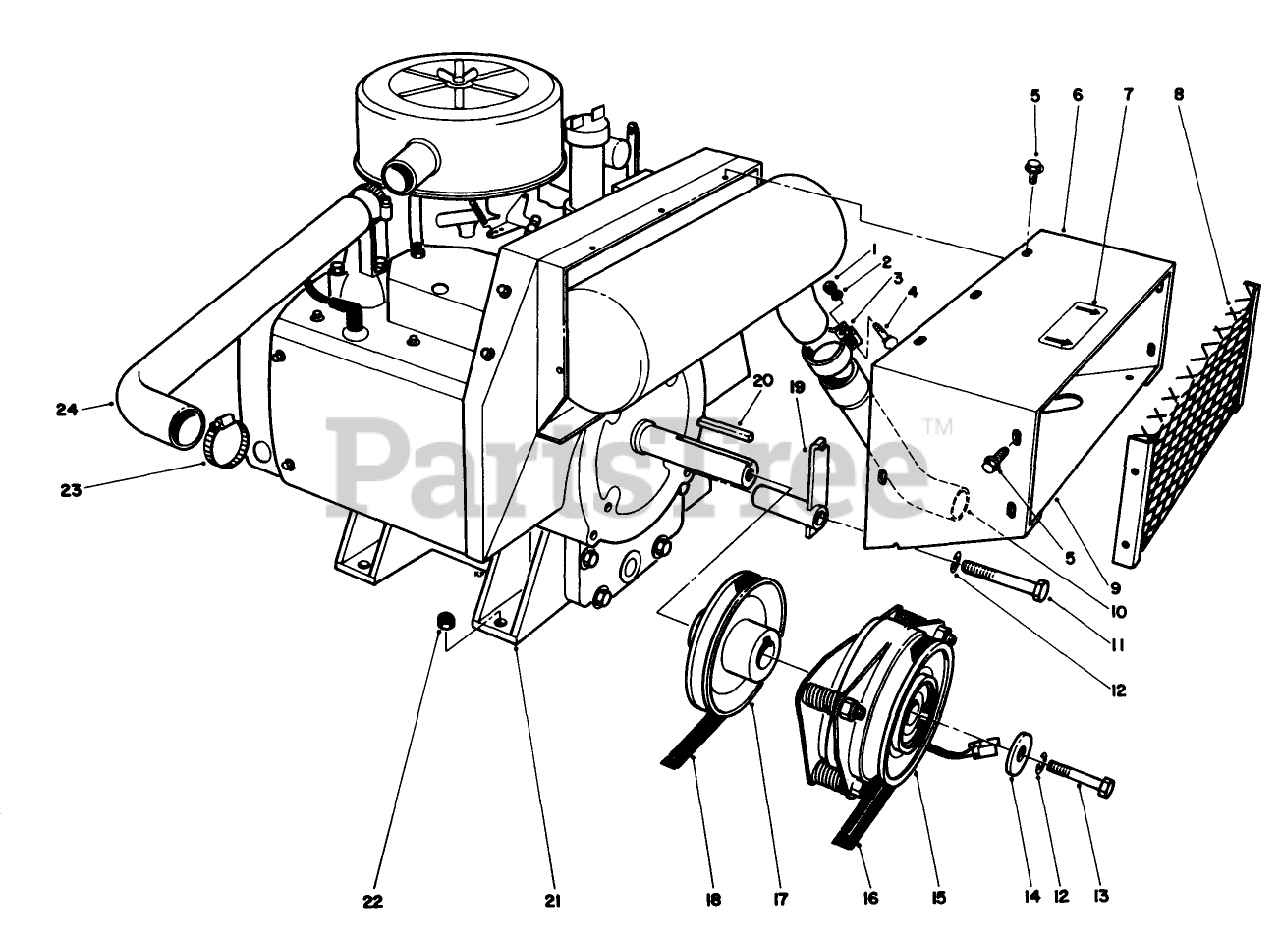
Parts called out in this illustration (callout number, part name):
1	NUT-HEX
2	Lockwasher
3	Clamp (Incl. Ref. #1-2 & 4)
4	SCREW-CARR
5	SCREW-HHFTF
6	ENGINE DUCT WA B
7	Decal-Hot
8	Screen
9	BOTTOM DUCT B
10	EXHAUST PIPE
11	SCREW-HH
12	WASHER-LOCK
13	SCREW-HH
14	WASHER-CLUTCH
15	BRAKE CLUTCH ASM
16	V-BELT, JACKSHAFT
17	ENGINE PULLEY
18	V-BELT, TRACTION
19	Anchor Bracket
21	Engine
22	NUT-LOCK, NI
23	CLAMP-HOSE
24	AIR CLEANER HOSE
